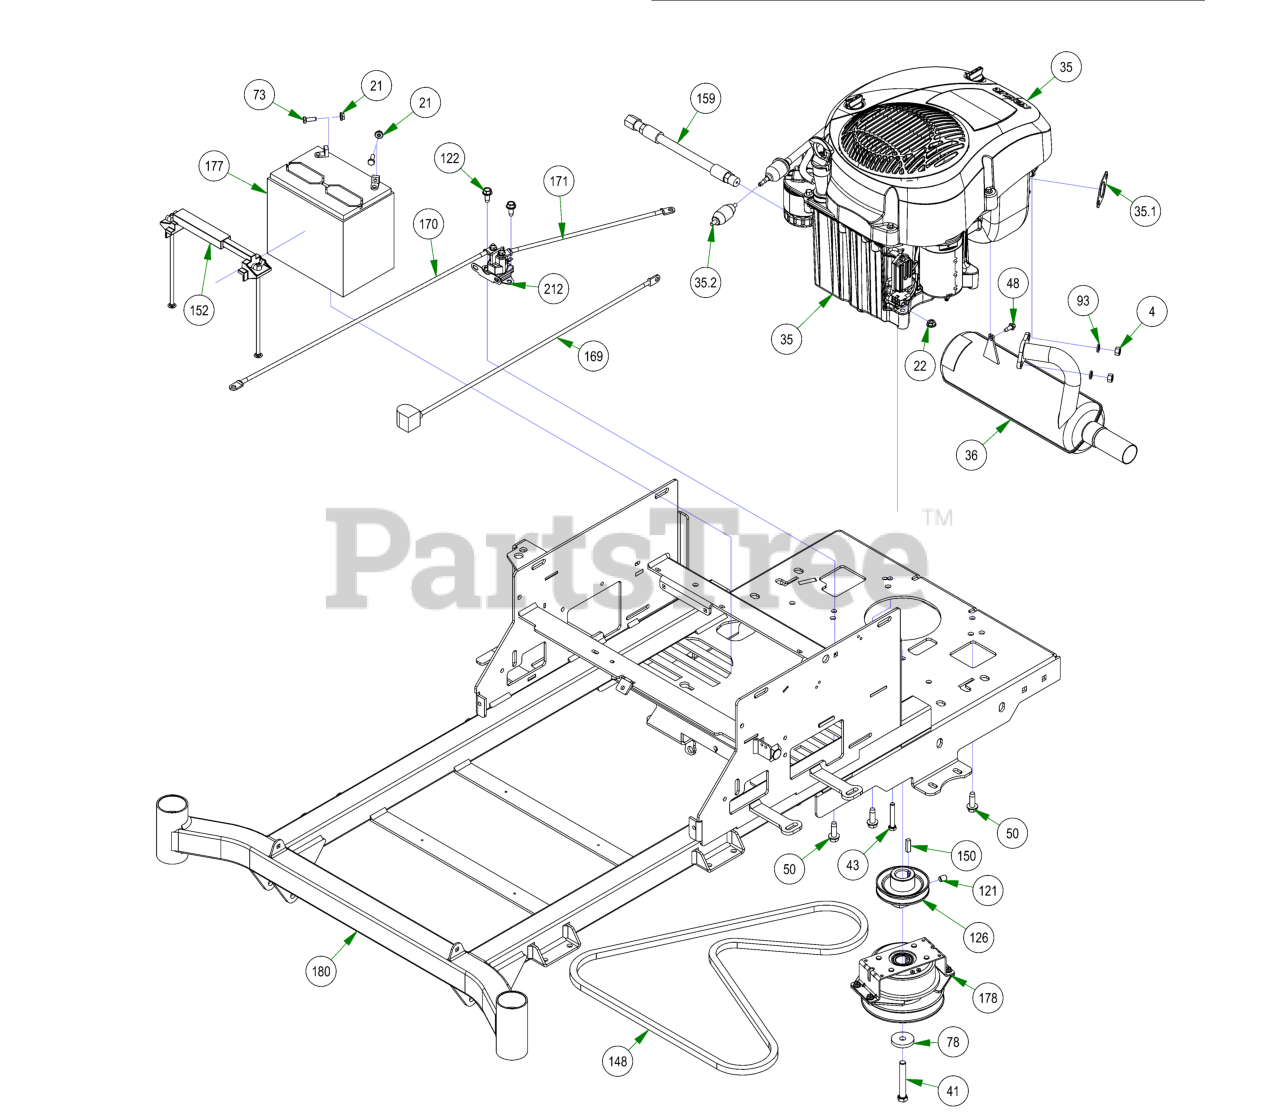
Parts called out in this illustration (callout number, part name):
4	M8-1.25 DIN 934 HEX NUT (CL.8) ZINC
21	1/4-20 HEX SERRATED FLANGE NUT HARD/ZINC
22	5/16-18 HEX SERRATED FLANGE NUT HARD/ZINC
35	2018 541cc Kohler 5400 Series Engine 19hp MZ
35.1	Exhaust Gasket
35.2	Universal Inline Fuel Filter
36	Kohler KS-590 Muffler
41	7/16-20x3” Hex Bolt GR 8 W/ Patch
43	5/16-18 X 2 HEX CAP SCREW (GR.5) ZINC
48	M6-1.0 X 16MM DIN 7500D HEX WASHER UNSLOT (TRI-LOB) TRS ZINC/WAX
50	3/8-16 X 1-1/8 HEX WASHER UNSLOT SERRATED (TRI-LOB) TRS ZINC YELLOW
73	1/4-20 X 3/4 HEX CAP SCREW (GR.5) ZINC
78	CLUTCH WASHER
93	5/16 SPLIT LOCKWASHER ZINC
121	3/8-16 X 1/2 SOCKET SET SCREW (CUP PT) PLAIN
122	5/16-18 X 3/4 HEX WASHER SLOT (F) TCS ZINC
126	3-3/4" Motor Pulley
150	1/4 X 1 SQ MACHINERY KEY 1018 STL PLN
152	Hold Down Assembly
159	Oil drain Hose
169	24 inch Black Cable – MZ/ZT
170	24" Red Battery Cable
171	12 in red battery cable
177	SP-35 Battery
180	2022 MZ/ZT 42"-48" Frame
